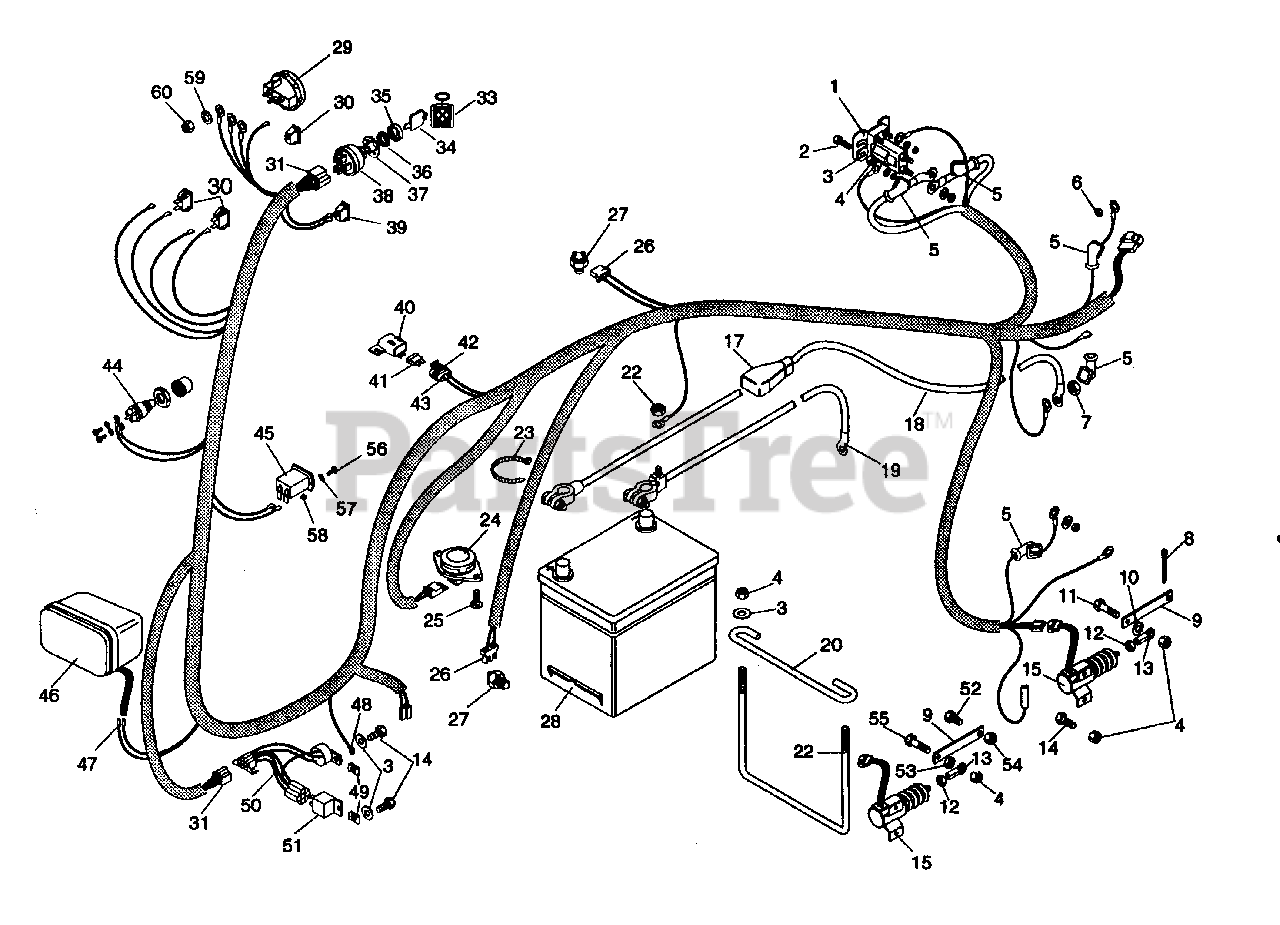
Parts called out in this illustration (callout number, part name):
1	SOLENOID
2	BLT-HEX .25-20 X .75 PL GR 5
3	WSHR-FL-STL .281 X .625 X .065
4	NUT-LK-NYL .250-20 PL
5	G-BOOT, INSULATOR
6	NUT-HEX M5 X .8 PL
7	NUT-HEX M8 X 1.25 PL
8	PIN-COTR .062 X .75 PL
9	PLT-STOP
10	WSHR-LOCK .250 REG.
11	BLT-HEX .25-20 X 1.00 PL GR 2
12	NUT-HEX-JAM .250-28
13	ROD END, FEMALE 1/4-28
14	BLT-HEX .25-20 X .63
15	SOLENOID, ENGINE STOP
16	HRNS, WIRING 22/30-H
17	CVR, BATTERY TERMINAL
18	CBL, POSITIVE CABLE
19	CBL, NEGATIVE BATTERY
20	ROD, HOLD DOWN
21	ROD, BATTERY
22	NUT-HEX .312-18
23	TIE WRAP, BLACK
24	SEAT SWITCH
25	SCR-MCH .25-20 X .50
26	CONN, 2-WIRE SWITCH
28	BATTERY, 24 FLTV
28	BATTERY, 12V 22F30GT
29	GA, WATER TEMPERATURE
30	SWITCH, BLANK
31	CONNECTOR
32	LIGHT, INDICATOR
33	KEY CHAIN
34	IGNITION SWITCH KEY
35	CAP - IGNITION SWITCH
36	NUT - PANEL .562-24 GRECO
37	WSHR-LOCK INT .563 X .040 PL
38	IGNITION SWITCH
39	SWITCH, LIGHT
41	FUSE, 25 AMP
42	TERM., FOR 14-16 GA WIRE
43	ASM, CONN WEATHER TIGHT
44	SWITCH, PREHEATER
45	HOUR METER
46	HEADLAMP, 3 X 5 HALOGEN
47	TERMINAL, MALE
48	TERM., RING TONGUE
49	NUT-SPEED .25-20
50	MODULE, TIME DELAY
51	RELAY
52	BLT-HEX .25-28 X .50
53	NUT-HEX .250-20 ZC
54	NUT-LK-CTR .250-28 TYP N
55	BLT-HEX .25-20 X 1.25 PL GR 2
56	SCR-SLT RND HD MACH 6-32 X 1/2
57	WSHR-LOCK INT .125 X .02 BL PL
58	NUT-HEX MACH #6-32
59	WSHR-LOCK 10 X .047 MED PL
60	NUT-HEX 10-32
